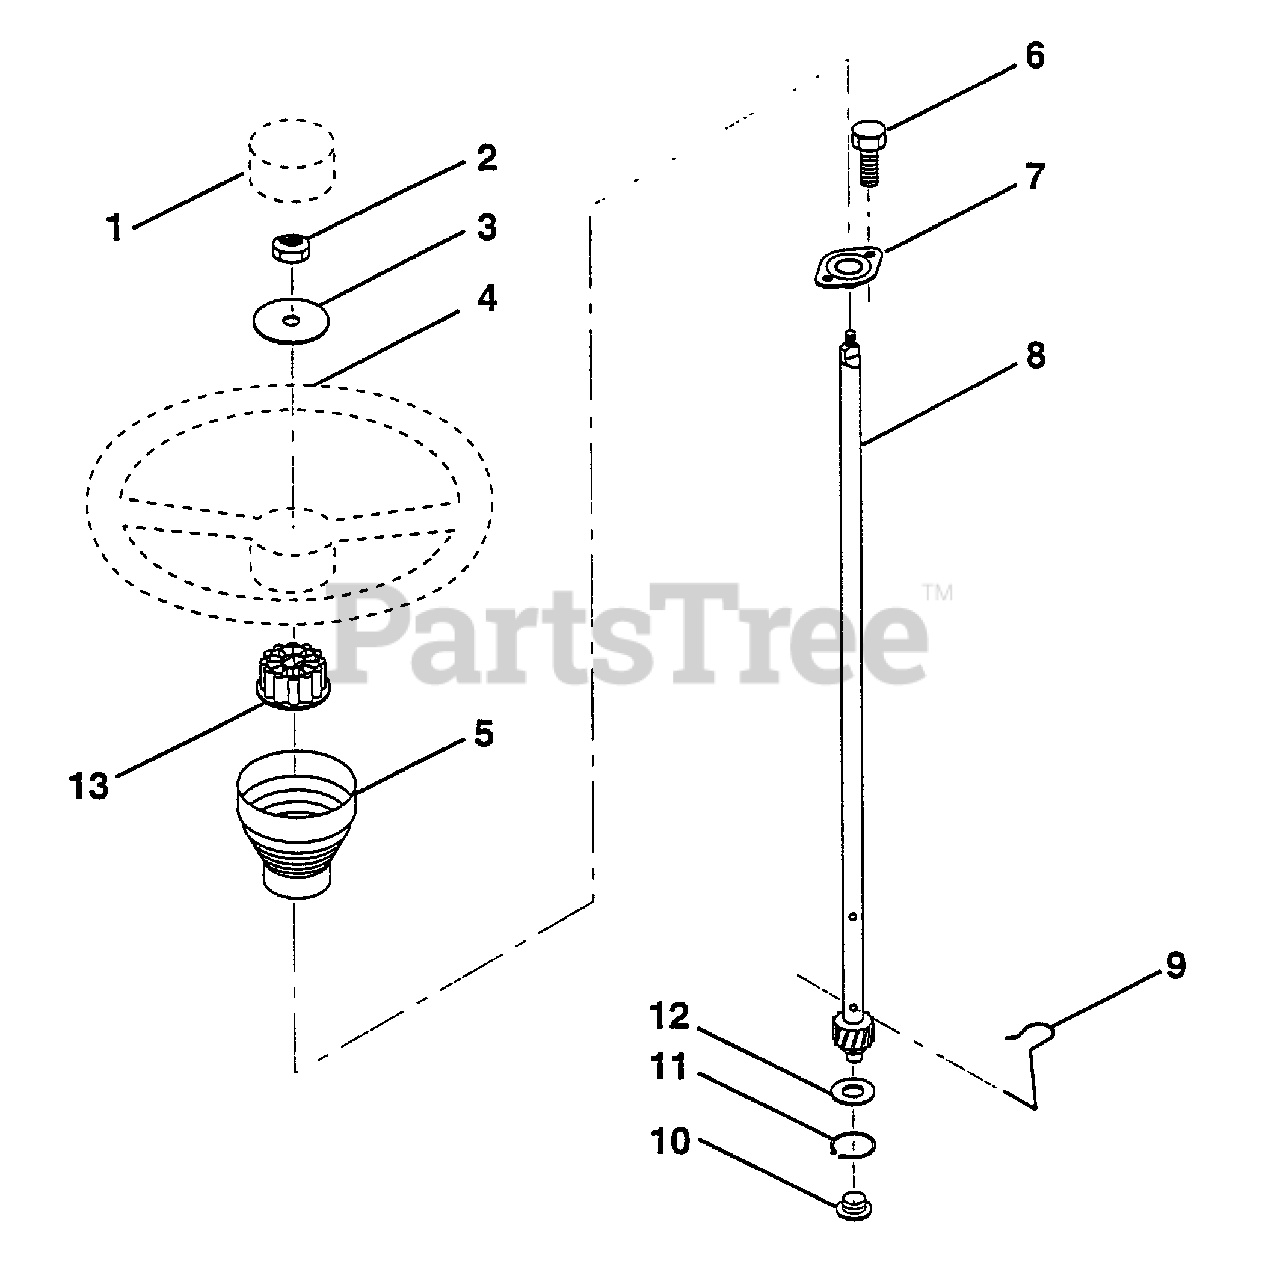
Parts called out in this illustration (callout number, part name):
1	Insert, Steering Wheel
2	Locknut 3/8-24 UNF
3	Washer 12/32 x 2-3/8 x 8 Gauge
4	Steering Wheel
5	Sleeve, Steering
6	Screw, Hex Head #10-16 x 1/2
7	Bushing, Steering
8	Shaft, Steering
9	Clip, Steering
10	Bushing, Lower, Steering
11	Ring, Retaining
12	Washer 21/32 x 1 x 16 Gauge
13	Adaptor, Steering Wheel
